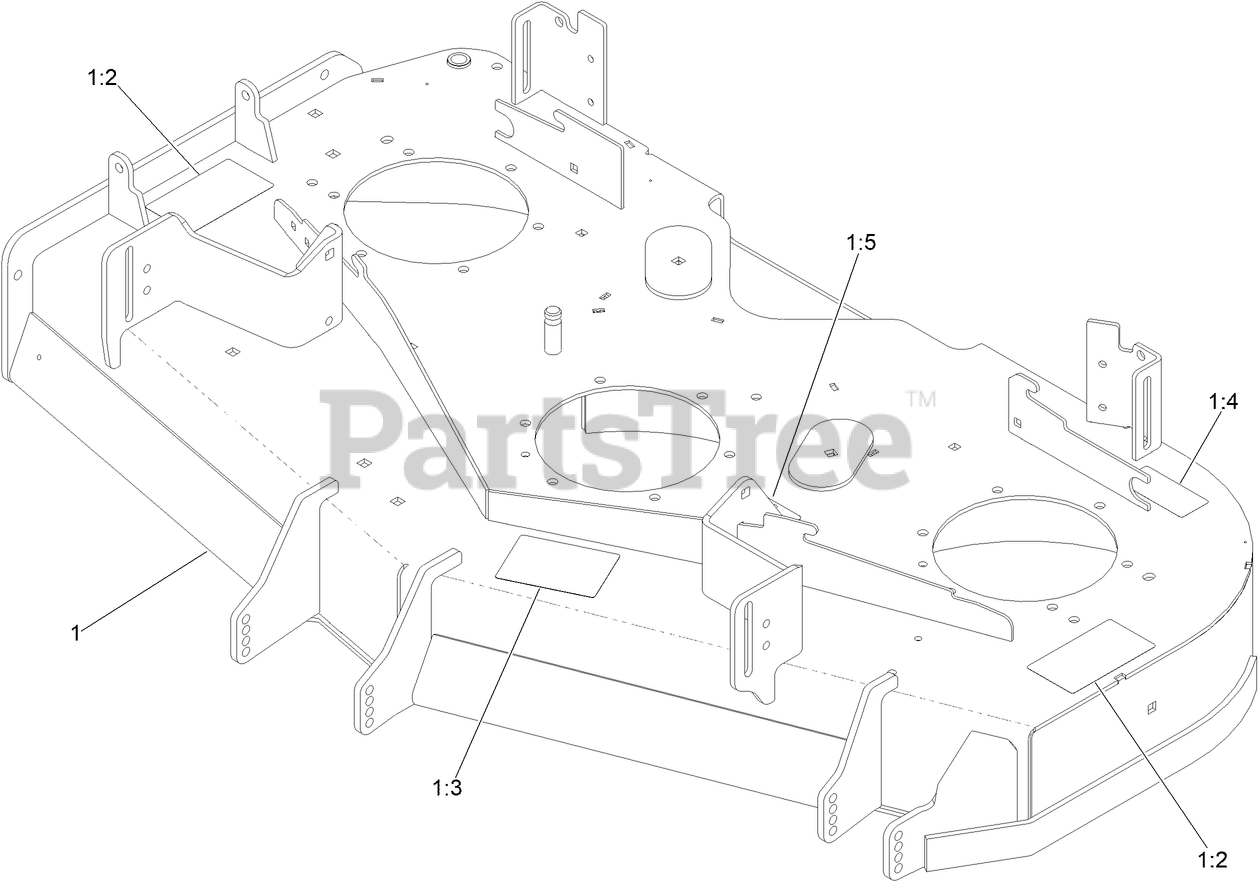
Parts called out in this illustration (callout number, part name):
1	Deck ASM W/Decals
1:2	DECAL-DANGER
1:3	DECAL-SCALP, ANTI
1:4	DECAL-BOLT TORQUE
1:5	DECAL-ROUTING, BELT
